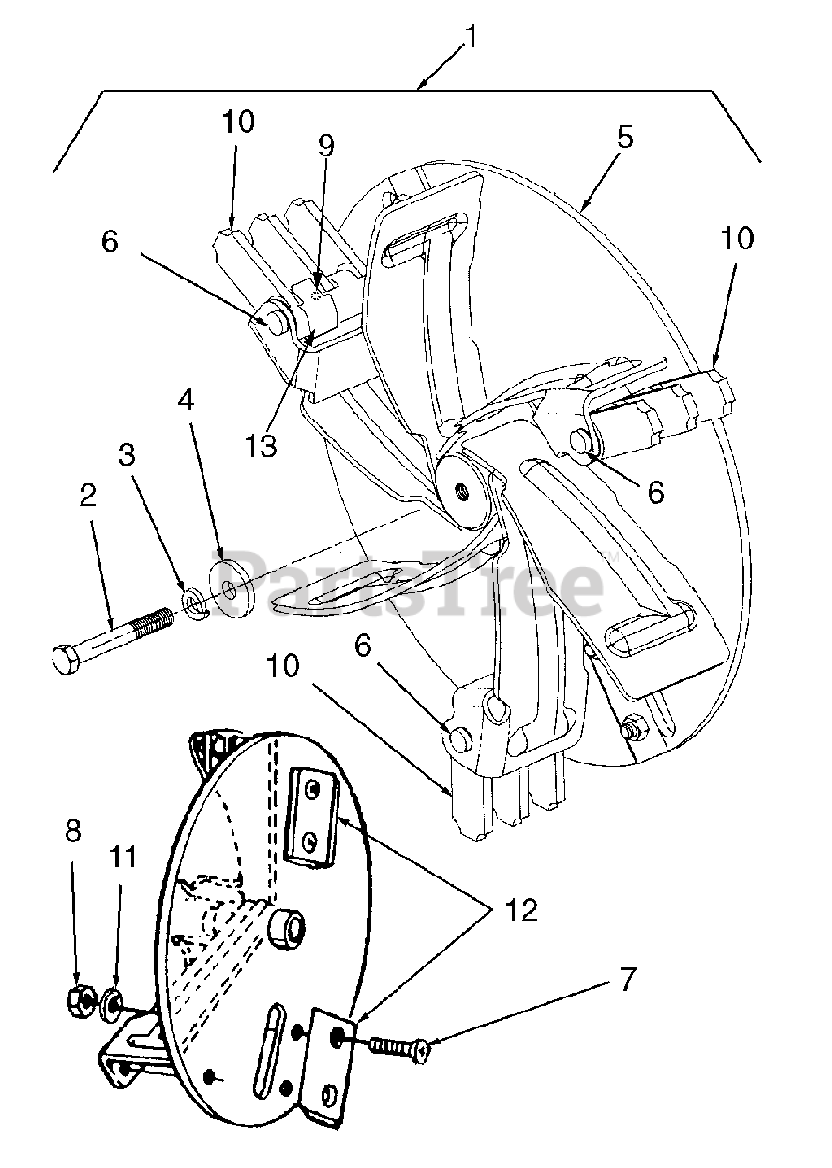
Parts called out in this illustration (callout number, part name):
1	Impeller Ass'y, Complete (103A)
2	Screw, Hex Cap, 3/8-24 x 2.75 GR5
3	Washer, Lock, 3/8 Heavy Duty
4	Washer, Flat, .406 x 1-1/4 HD
5	Impeller Assembly (103A)
6	Pin, Clevis
7	Screw, Flat Hd. Cap, 5/16-24 x 1.0
8	Nut, Hex Insert Lock, 5/16-24
9	Pin, Spirol,.156x 1.000 Std.
10	Blade, Flail
11	Washer, Lock, 5/16
12	Blade, Chipper
13	Clip, Retainer
